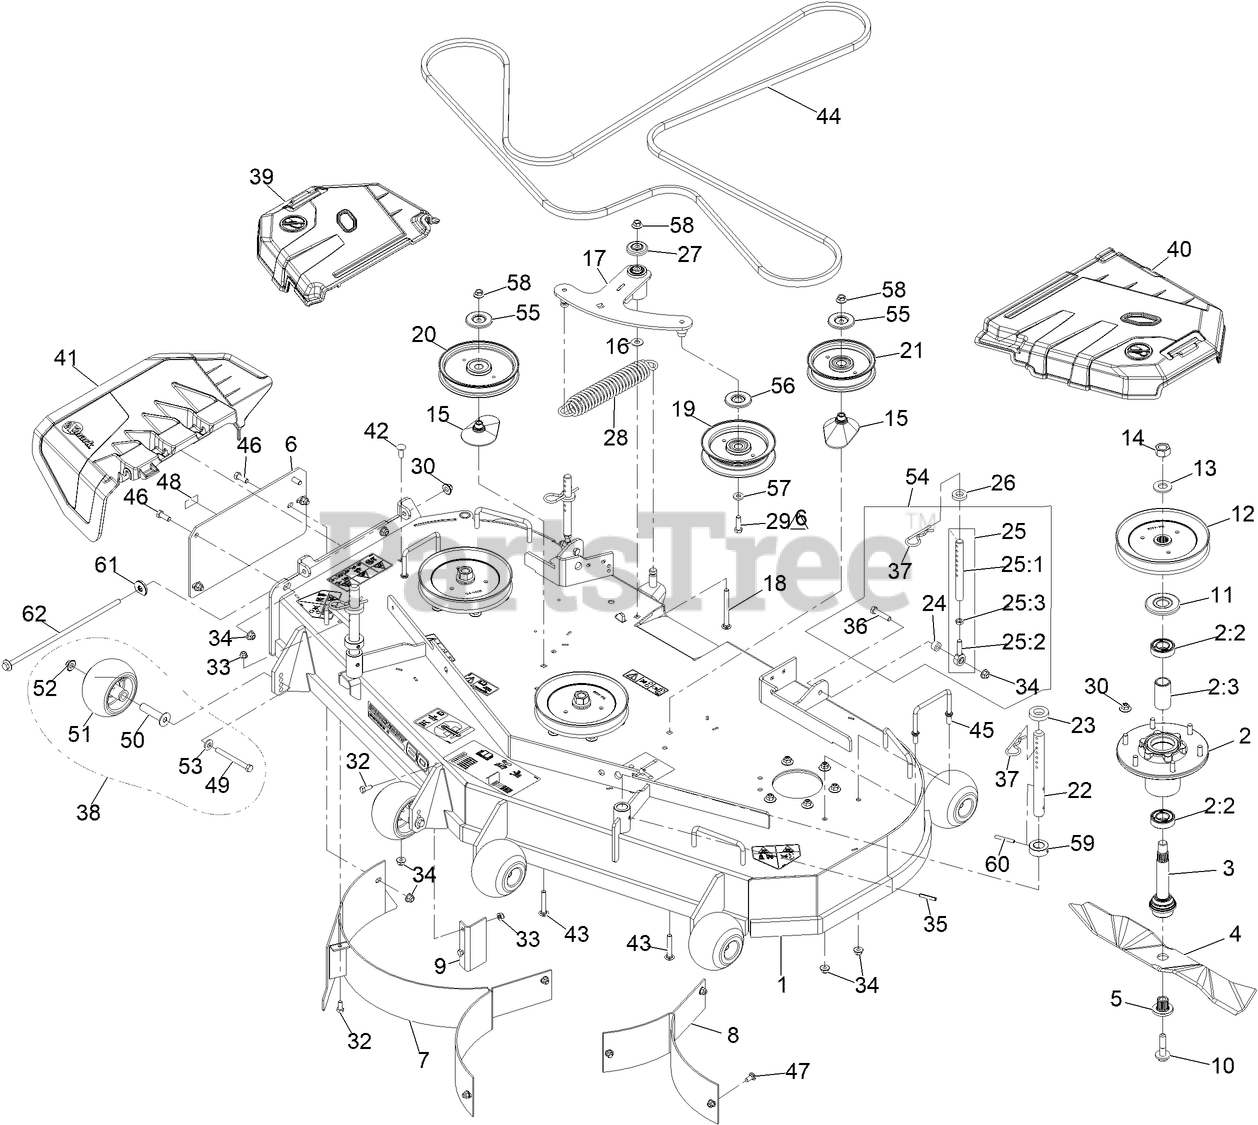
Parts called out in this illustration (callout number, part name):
1	ASM, Deck W/ Decals, 60"
2	ASM-CUTTER HSG WITH BEARINGS
2:2	BEARING-BALL
2:3	SPACER-BEARING
3	ASM-SPINDLE AND SEAL
4	Blade-Extreme 2, 20.50"
5	BUSHING,SPLINED
6	XREF 1-633957-01 (EXMARK)
7	BAFFLE WLD RH MULCH
8	BAFFLE WLD LH MULCH
9	XREF 1-633956-03 (EXMARK)
10	SCREW,SEMS 1/2-20 X 2.19
11	GUARD,BEARING TOP .989
12	SHEAVE,BLADE DRIVE 7.25
14	NUT-HEX
15	SPACER-PULLEY
16	WASHER-FLAT
17	ASM, DECK IDLER
18	SCREW-CARR
19	IDLER-PULLEY, FLAT
20	Idler-Pulley, Flat
21	Pulley-Idler, Flat
22	ROD, DECK SUPPORT
23	SPACER-DECK SUPPORT
25:1	LINK,SUPPORT
25:2	BALLJOINT
25:3	NUT-HJ
27	GUARD-TOP
28	SPRING-EXTENSION
29	SCREW-HH
30	Nut-Nyloc 3/8-16 Flg
32	SCREW-HH
33	NUT-HF, NI
34	NUT-HF, NI
36	SCREW-HH
37	PIN,HAIR COTTER
38	KIT, ANTI-SCALP ROLLER
39	SHIELD, RT
40	SHIELD, LT
41	Chute-Deck Discharge
42	SCREW-CARR
43	BOLT-CARR, SHORT NECK
45	WIREFORM-COVER
46	SCREW-HH
47	BOLT-CARR
48	Decal-Patent Ttco.Com
49	SCREW-HH 3/8-16 X 3 3/4 GR 8
50	AXLE, ROLLER
51	ROLLER-SCALP, ANTI
52	Nut-Nyloc 3/8-16 Flg
53	WASHER-BELLEVILLE
54	KIT,SUPPORT LINK W/PIN
55	SHIELD-DUST
56	SHIELD-GUARD, DUST
59	COLLAR, DECK HEIGHT PIN
60	PIN-ROLL
61	Retainer, Chute
62	Pin, Chute
